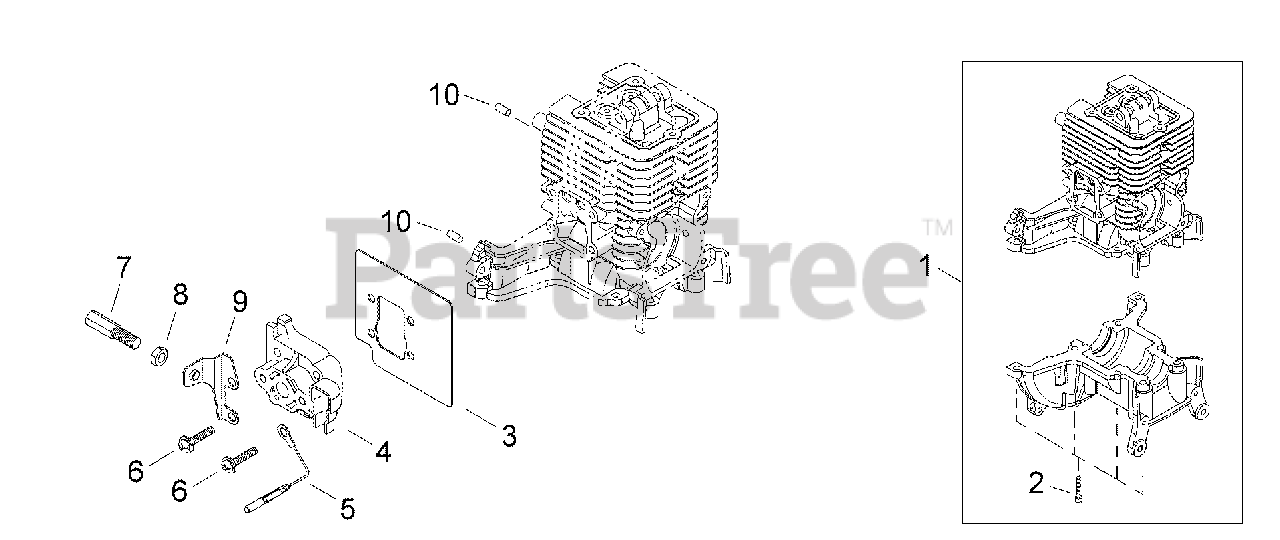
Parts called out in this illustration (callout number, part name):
1	CYLINDER BLOCK SET
2	SCREW - 5X16
3	DEFLECTOR, HEAT
4	VALVE, REED
5	LEAD - GROUND
6	SCREW - 5X25
7	NUT, CABLE ADJUST
8	LOCKNUT - 6
9	BRACKET, THROTTLE CABLE
10	PIN - LOCATING
